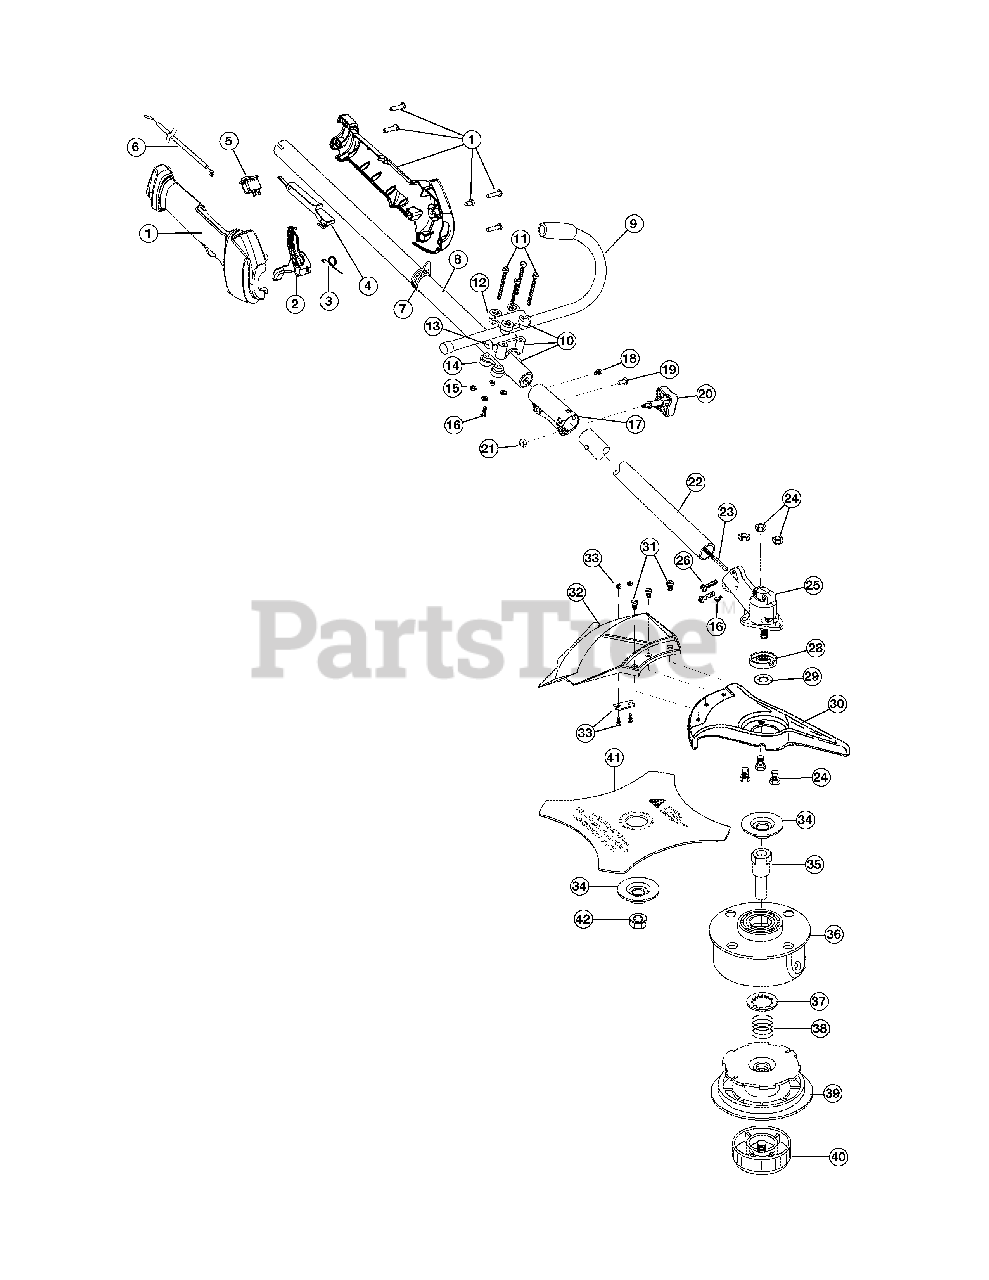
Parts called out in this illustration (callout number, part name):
1	Throttle Housing Assembly (includes 2-5)
2	Throttle Trigger
3	Throttle Trigger Spring
4	Throttle Trigger Lock-Out
5	Switch Assembly
6	Throttle Cable Assembly
7	Harness Clip
8	Upper Drive Shaft Housing Assembly
9	J-Handle Assembly
10	Handle Bracket Assembly (includes 11-16)
12	Upper Handle Clamp
13	Middle Handle Clamp
14	Lower Handle Clamp
16	Anti-Rotation Screw
17	Split Boom Coupler (includes 18-21)
20	Adjustment Knob
21	Knob Retaining Nut
22	Lower Drive Shaft Housing Assembly
23	Lower Flexible Drive Shaft
24	Shield Mount Screw Assembly
25	Gearbox Assembly (includes 16 & 26-28)
26	Gearbox Mounting Hardware
28	Spacer, Gearbox
30	Blade Shield/Shield Mount
31	Shield Mounting Screw
32	Shield Assembly (includes 33 )
33	Blade Assembly
34	Retaining Washer
35	Spool Shaft
36	Outer Spool Assembly
37	Retainer
40	Bump Head Knob Assembly
41	4-Tooth Blade
